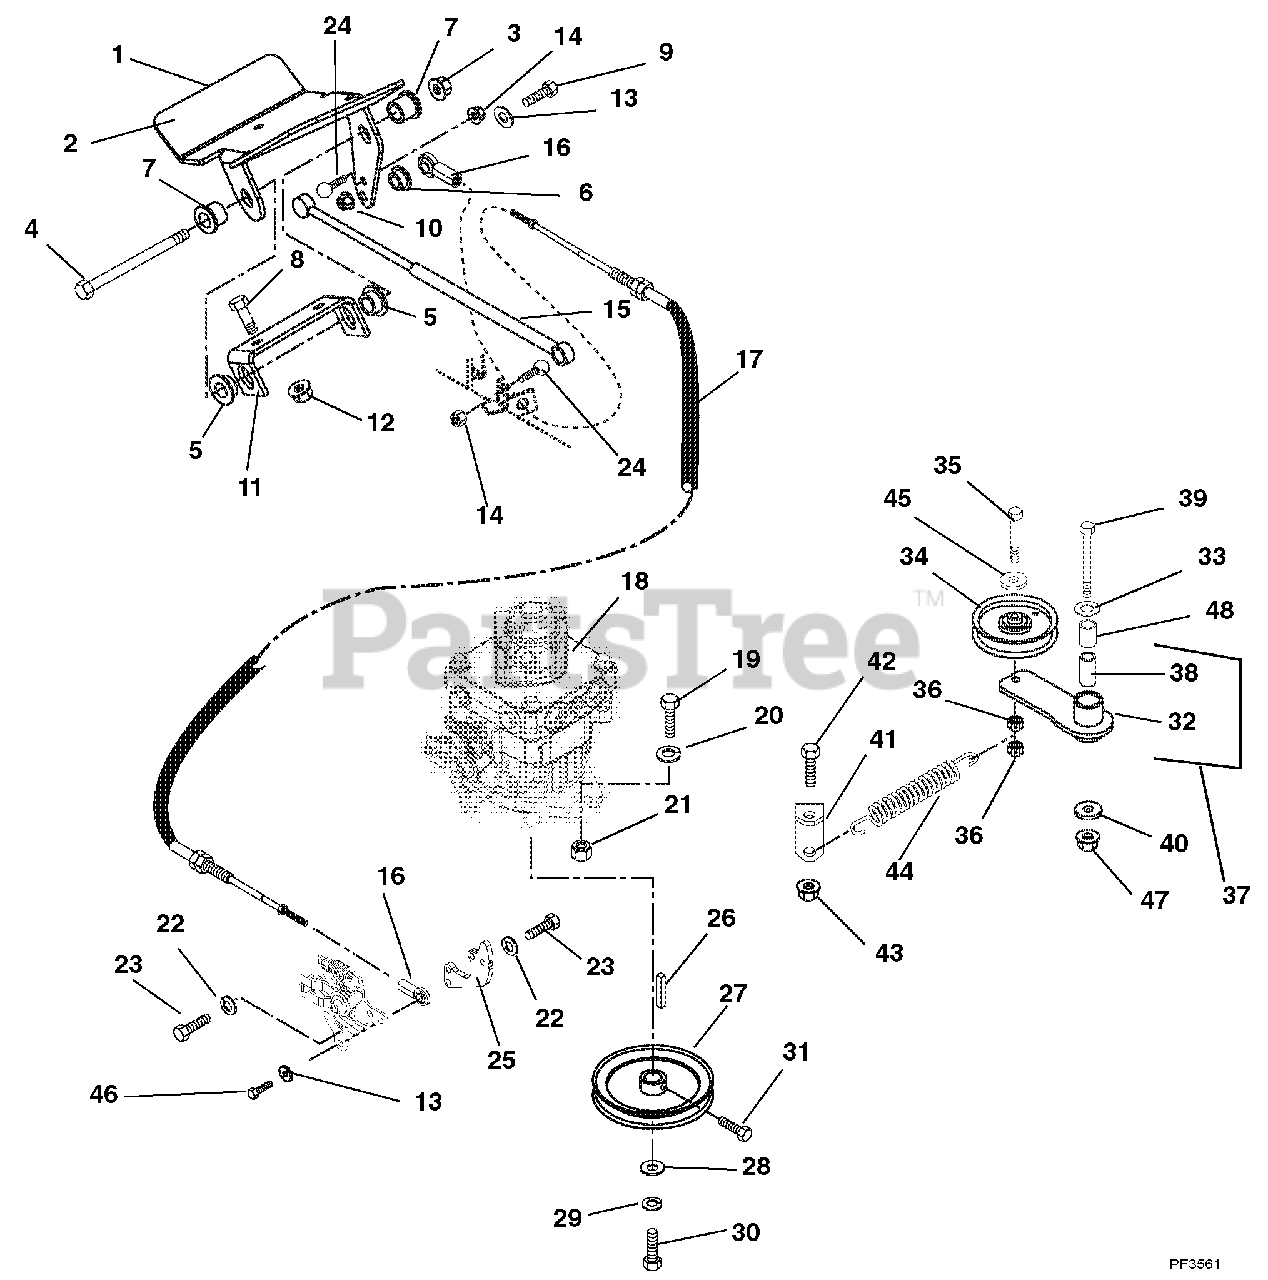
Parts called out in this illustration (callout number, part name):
1	Pedal, Direction Control
2	Pad, Foot Clutch Pedal
3	Nut-Locking-Top-Flange .50-13
4	Bolt-Hex .50-13 x 6.50 Grade 5
5	Bushing, Flange-Nylon .762 x 1.00 x .58 x 1.48
6	Bushing-Flange .265 x .437 x .250 x .750
7	Bushing, Flange-Nylon .515 x .75 x .745 x 1.00
8	Bolt, Hex .38-16 x 1.00 Grade 5
9	Bolt-Hex .25-20 x 1.00 Grade 5
10	Nut-Locking-Top-Flange .25-20
11	Bracket, Control Pedal
12	Nut-Locking-Top-Flange .38-16
13	Washer-Flat-Steel .28 x .62 x .065
14	Nut-Locking-Top-Flange .31-18
15	Dampener Control
16	Rod End, Female .25 RH
17	Cable, Forward-Reverse Control
18	Pump (Hydro-Gear Bi-Directional RTN PW-1KCC-JB1X-XXXX)
19	Bolt-Hex .50-13 x 1.50 Grade 5
20	Washer-Flat-Steel .531 x 1.06 x .095
21	Nut-Locking-Top-Flange .50-13
22	Washer-Locking .31 x .078
23	Bolt-Hex .31-18 x .50 Grade 5
24	Stud, Ball
25	Plate, PM320 Return Cam
26	Key-Straight 5mm x 5mm x 30mm
27	Sheave, Pump
28	Washer-Flat-Steel .281 x 1.000 x .063
29	Washer-Locking .25 x .062 Regular
30	Bolt-Hex M6 x 1.0 x 12
31	Bolt-Hex .25-20 x .50 Grade 5
32	Arm, Idler Pivot
33	Bushing, Spacer .505/.500 x .999/.996 x 2.05/2.03
34	Idler-V 4.00 x .38
35	Bolt-Hex .38-16 x 2.25 Grade 5
36	Nut-Locking-Center .38-16
37	Assembly, Idler Pivot Arm (Contains Items 38 and 32)
38	Bushing, 1.00 x 1.125 x 1.937
39	Bolt-Hex .50-13 x 4.00 Grade 5
40	Washer-Flat Steel .515 x 1.625 x .250
41	Anchor, Spring Idler
42	Bolt-Hex .38-16 x 1.00 Grade 5
43	Nut-Locking-Top-Flange .38-16
44	Spring, Extension
45	Washer-Flat-Steel .406 x .812 x .065
46	Bolt-Hex .20-20 x 1.25 Grade 5
47	Nut, Locking Center .50-13
48	Washer, Flat Steel .511 x 1.441 x .125
